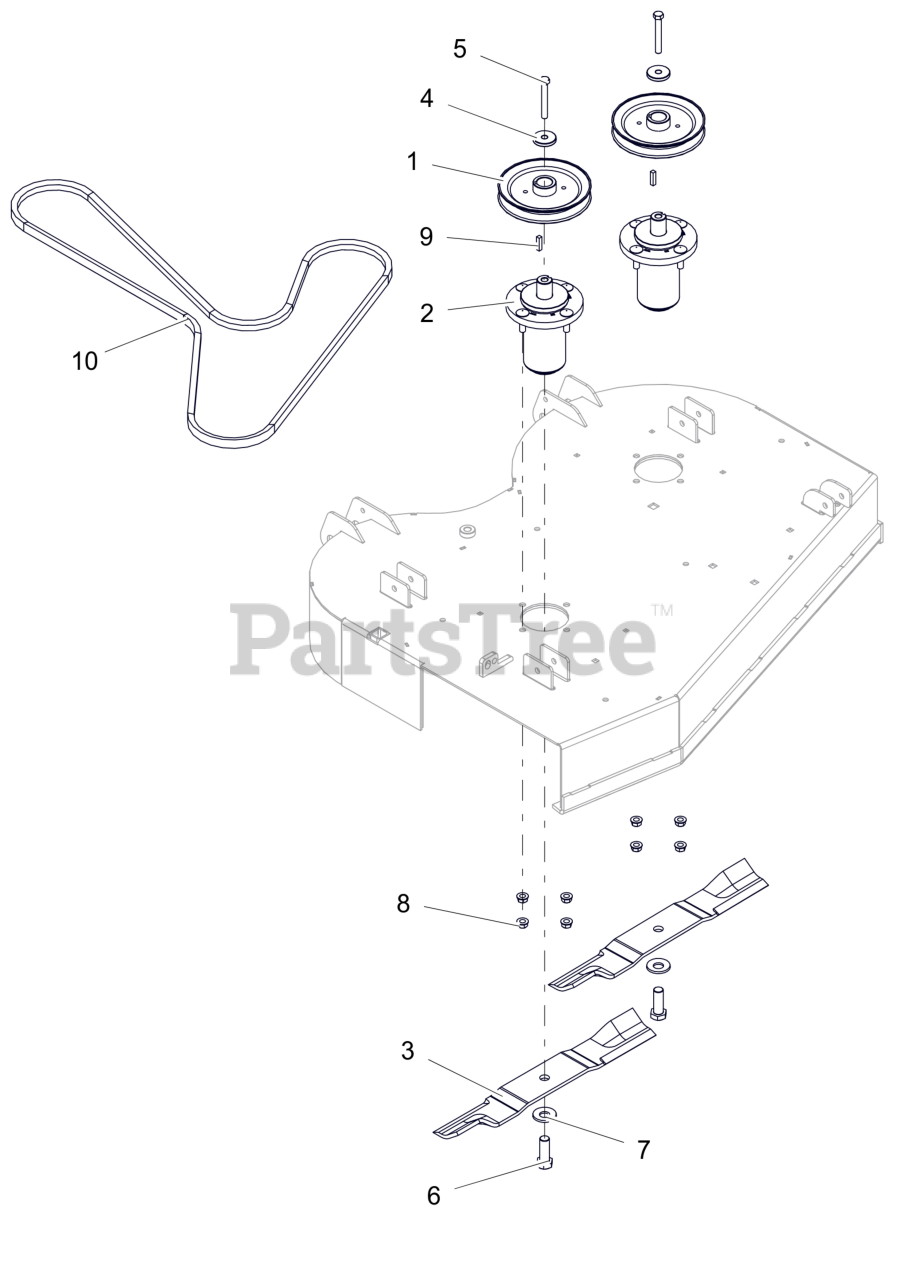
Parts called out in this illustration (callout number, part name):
1	PULLEY, V-1" ID X 6.00 OD
2	ASM, MAINT FREE ALUM SPINDLE
3	BLADE, 18.00" MOWER (HI-LIFT)
4	RETAINER, SHEAVE
5	BLT, HEX .38-16X2.75 G8 ZCC
6	BLT, HEX .62-18X1.75 G8 ZCC
7	WSHR-BLVL .669X1.535X.138
8	NUT-LK-CTR-FLG .375-16 GF ZCC
9	KEY, SQ .25X.25X1.00 RC 40-50
10	V-BELT, B RAW EDGE EPDM
